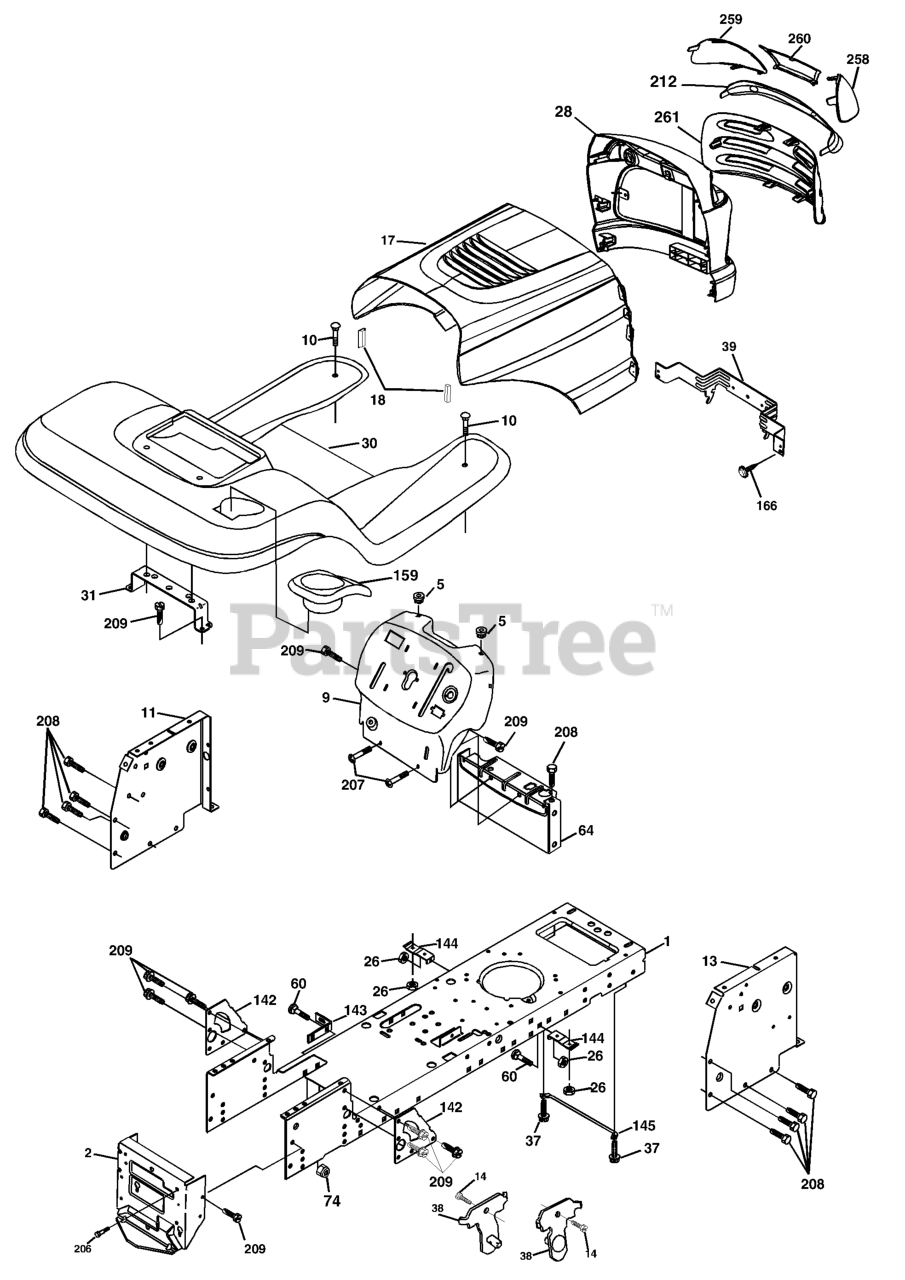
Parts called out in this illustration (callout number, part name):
1	CHASSIS STAMPING
2	DRAWBAR, 12GA
5	BUMPER.RUBBER.HOOD
9	DASH SILKSCR.
10	BOLT D
11	PANEL.DASH.LH.LTX
13	PANEL DASH RH
14	SCREW LT
17	HOOD
18	BUMPER.HOOD.LARGE.1.75"
26	NUT
28	GRILL/LEN.ASM.DL.HUSQ
30	FENDING
31	BRACKET.SUPPORT.FENDER
37	Screw Thdrol 6/16-18 x 1/2 TYT
38	BRACKET.ASM.PIVOT.MOWER.REAR
39	BRACKET PIVOT LASER
60	Bolt Rd Hd Sqnk 3/8-16 Unc x 3/4
64	DASH LOWER
142	PLATE REINFORCEMENT
143	BRACKET, SWAYBAR CHASSIS
144	BRKT, FOOT REST
145	ROD PIVOT CHASSIS/HOOD
159	CUPHOLDER
166	SCREW
206	SHOULDER BOLT 5/16-18TT
207	SCREW, 5/16-18 X 1/2
208	SCREW 3/8-16X1/2
209	SCREW, 3/8-16X3/4
212	INSERT.LENS.REFLECTIVE
258	LENS LH
259	LENS LH
260	COVER.LENS.HUSQ.( HAVE GRAY)
261	INSERT GRILLE
